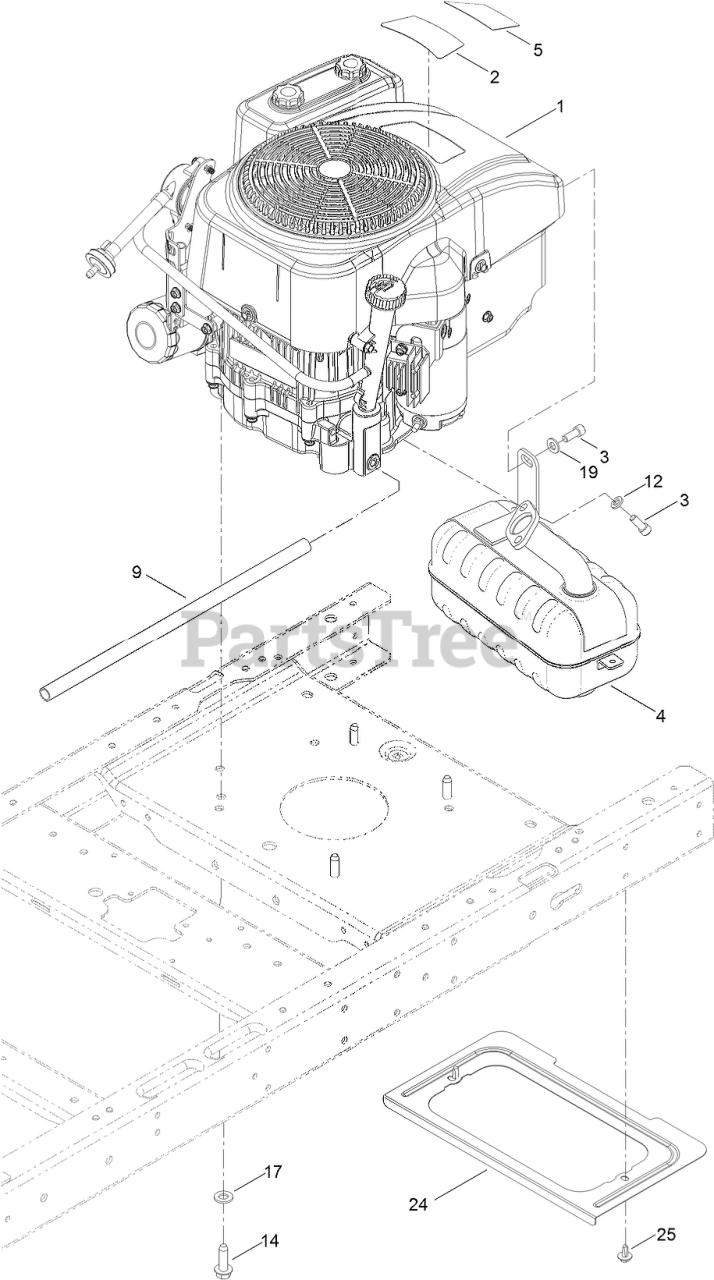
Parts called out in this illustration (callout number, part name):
1	ENGINE-1P92F-1
2	DECAL-ENGINE
3	SCREW-HSH
4	MUFFLER
5	DECAL-DISPLACEMENT, ENGINE
9	TUBE-DRAIN, OIL
12	WASHER-LOCK
14	SCREW-TAPTITE
17	WASHER-FLAT
19	WASHER-PLAIN
24	SHIELD-HEAT
25	SCREW-HHFTF
